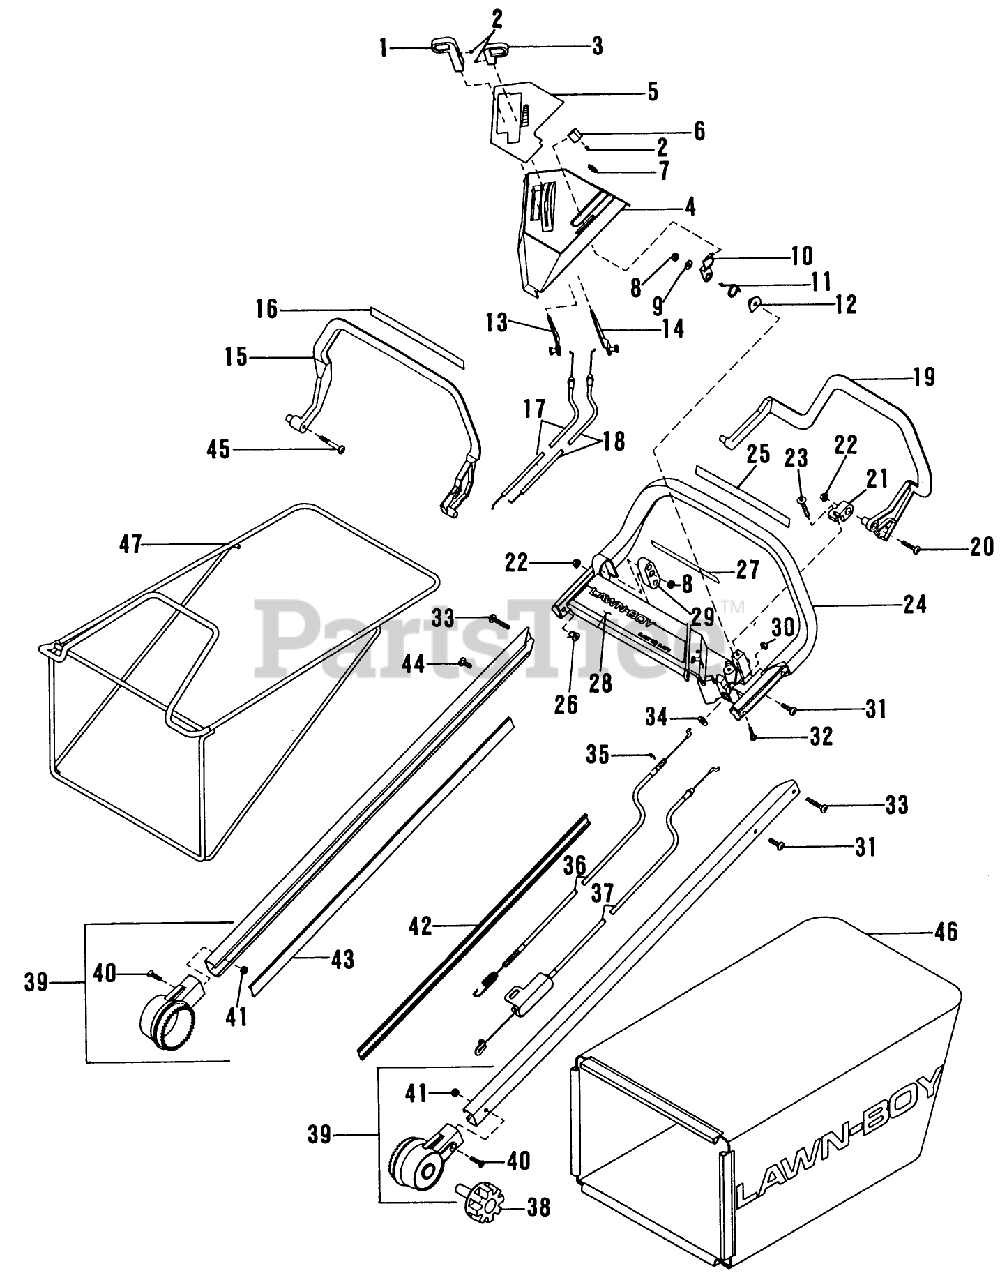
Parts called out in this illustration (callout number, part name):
8	LOCKNUT E
10	BBC LATCH LB
11	SPRING
17	CABLE AY. WESCON
18	CABLE
19	BAIL-S.P. *
21	PIVOT BAIL PL
22	LOCKNUT FLAN
29	BLOCK BAIL PL
31	SCREW-CROSS RECESS
33	SCREW-TRUSS
37	CABLE AY WESC
38	KNOB-HDLE MT.ASM*B
41	LOCKNUT FLAN
46	REPL BAG FOR 684190
